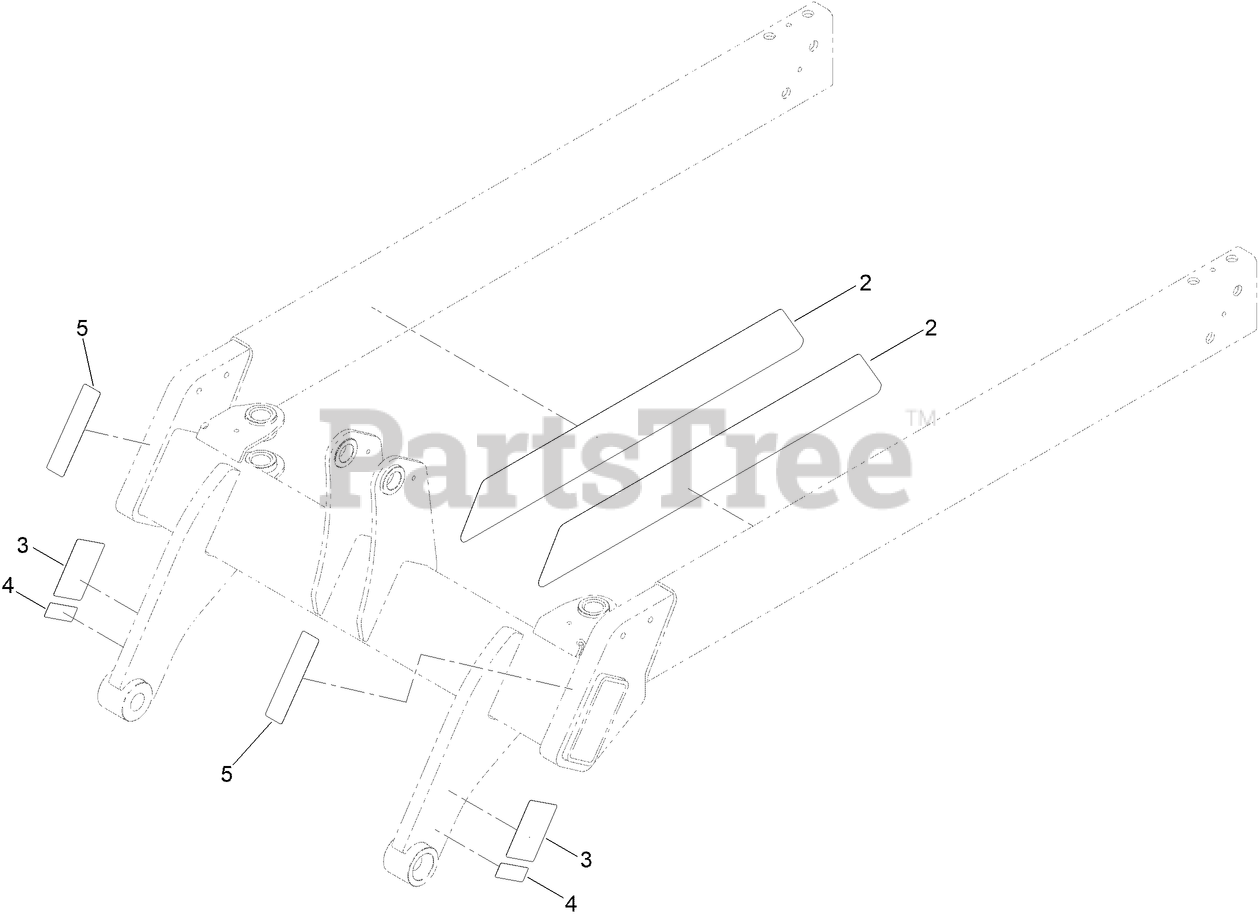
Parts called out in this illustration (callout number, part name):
2	DECAL-EXTENSION
3	DECAL-WARNING, BUCKET
4	DECAL-WARNING, PINCH POINT
5	TAPE-REFLECTIVE
